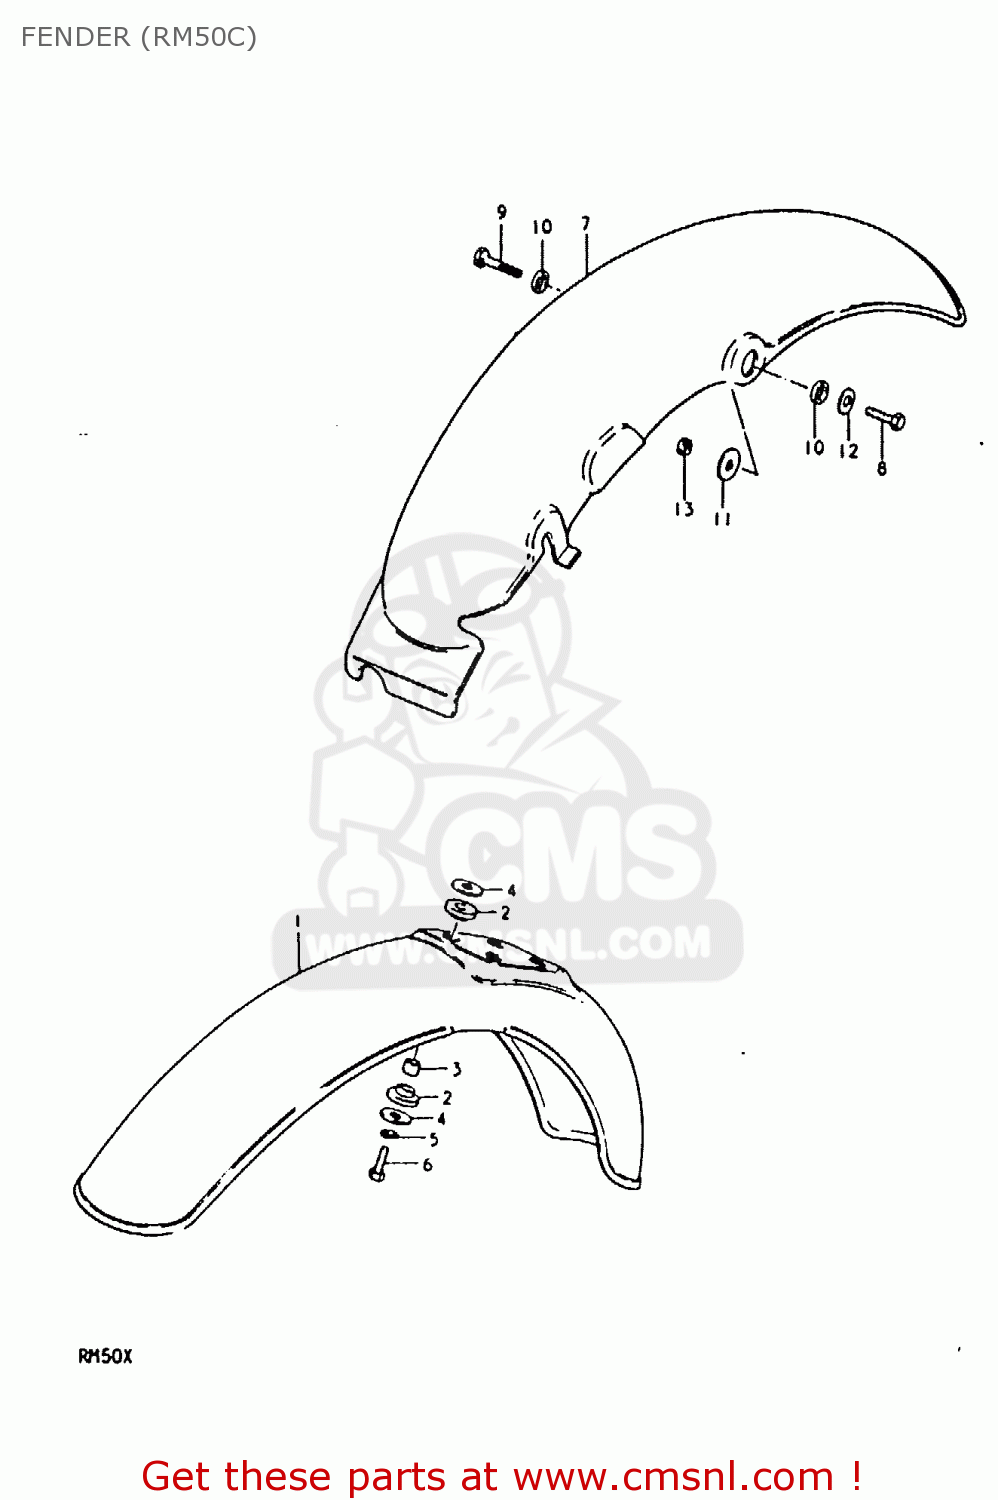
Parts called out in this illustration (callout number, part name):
1	FENDER,FRONT
2	CUSHION
3	SPACER (6.8X10X10)
4	WASHER (6.5X20X1.2)
5	LOCK WASHER
6	BOLT
7	FENDER,REAR
8	BOLT
9	BOLT (8X30)
10	SPACER(8.5X12X2.5)
11	WASHER (8.2X20X1.6)
12	WASHER
13	NUT
